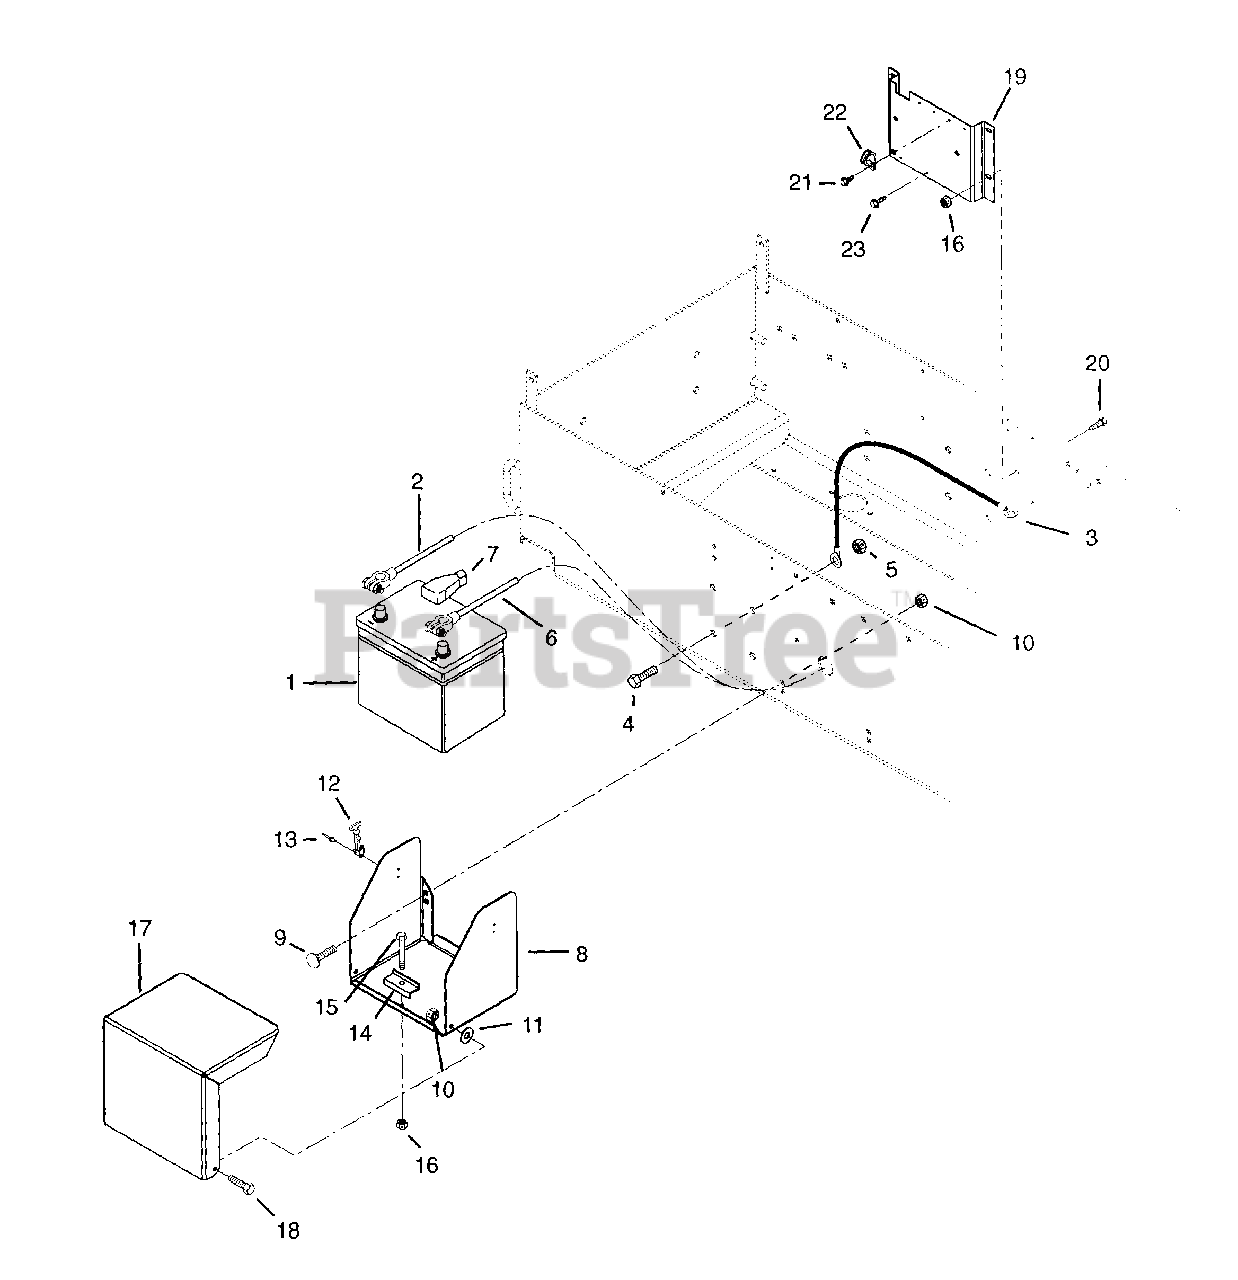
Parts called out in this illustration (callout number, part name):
1	Battery
2	Cable, Negative Battery
3	Ground Strap
4	Bolt-Hex .50-13 x 1.00 Grade 5
5	Nut-Locking-Center .50-13
6	Cable, Positive Battery
6	Cable, Battery to Magneto Switch
7	Cover, Battery Terminal
8	Weldment, Battery Box
9	Bolt-Round Head Square Neck .31-18 x .75 Grade 5
10	Nut-Locking-Center .31-18
11	Washer-Flat-Steel .344 x .688 x .065
12	Draw Latch, Rubber with Catch
13	Rivet-Pop .125 x .357 Dome
14	Kubota Battery Clamp
15	Bolt-Hex .25-20 x 1.00 Grade 5
16	Nut-Locking-Center .25-20
17	Weldment, Battery Box Cover
18	Bolt-Hex .31-18 x .50 Grade 5
19	Bracket, Electrical Component
20	Bolt-Hex .25-20 x .50 Grade 5
21	Screw-Tapping 10-24 x .375 Hex Washer Head
22	J-Clamp
23	Screw-Tapping 10-24 x .75 Hex Washer Head
